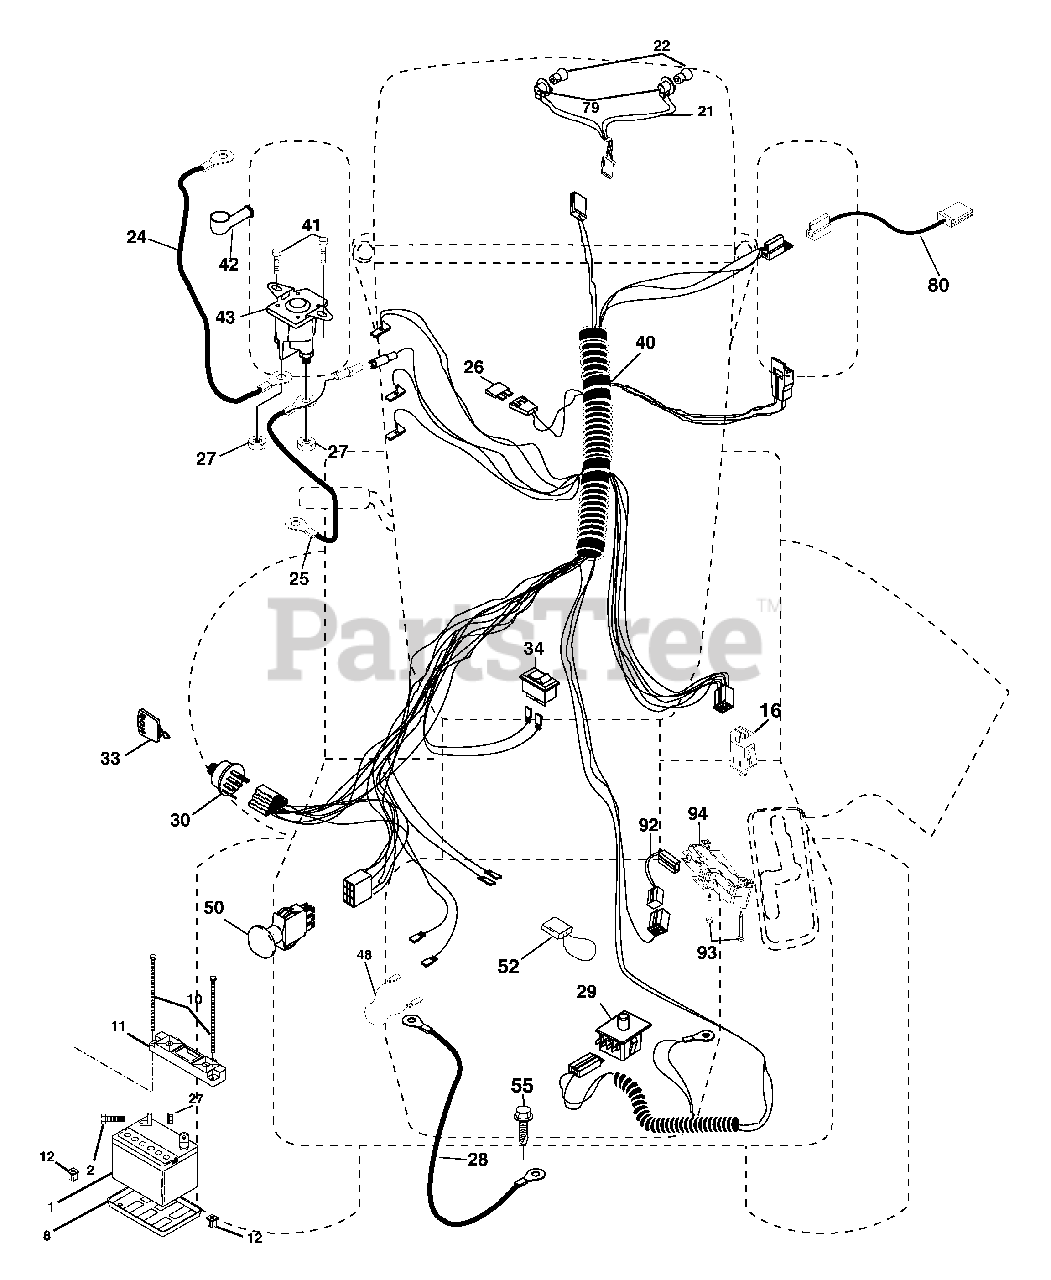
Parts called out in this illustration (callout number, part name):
1	Battery
2	Bolt Hex Hd 1/4-20 unc x 3/4
8	Tray Battery
10	Bolt Battery Front 1/4-20 x 7.5
11	Holddown Battery
12	Nut Push Nylon 1/4
16	Switch Interlock
21	Harness Socket Light
22	Bulb, Light # 1156
24	Cable Battery
25	Cable Battery 6 Ga. Red w/16 wire
26	Fuse
27	Nut Keps Hex 1/4-20 unc
28	Cable Ground 21" Blk 6 Ga.
29	Switch Seat
30	Switch Ign
33	Key Ign Molded Generic
34	Switch Light/Reset
40	Harness Ign
41	Bolt Fin Hex 1/4-20 unc x 1/2
42	Cover Terminal Red
43	Solenoid
48	Adaptor Ameter
50	Switch PTO
52	Protection Loop
55	Screw Thdrol 5/16-18 x 1/2
79	Socket Asm Bulb Twistlock
80	Harness Clutch EVX
92	Harness Pigtail Reverse Switch
93	Screw Plastite 10-14 x 2.0
94	Module Revers ROS
